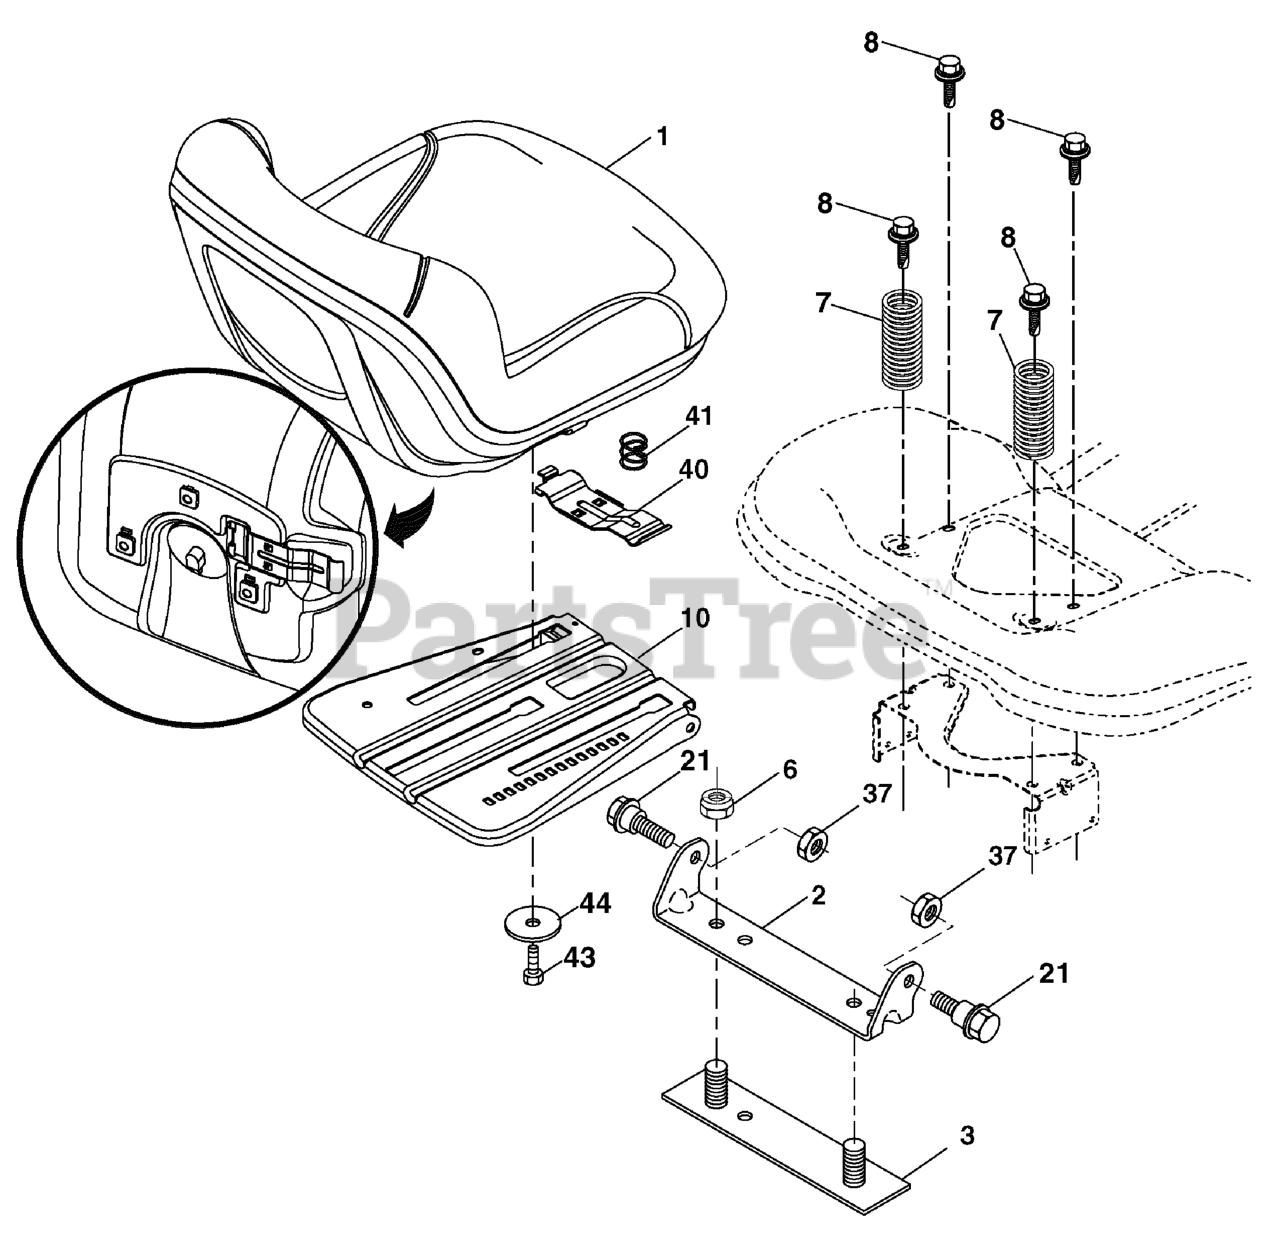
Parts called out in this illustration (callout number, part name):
2	Bracket Pivot Fender
3	Strap, Asm Fender
6	Nut, Lock w/Ins. 3/8-16 unc
7	Spring, Seat Cprsn
8	Bolt 5/16-18 unc x 3/4 w/Sems
10	Pan, Seat
21	Bolt, Shoulder 5/16-18
37	Nut, Lock 5/16-18 unc
40	Handle Slide
41	Spring Latch
43	Bolt 3/8-16 unc x 3/4
44	Washer 13/32 x 2 3/8 x 12 Ga.
